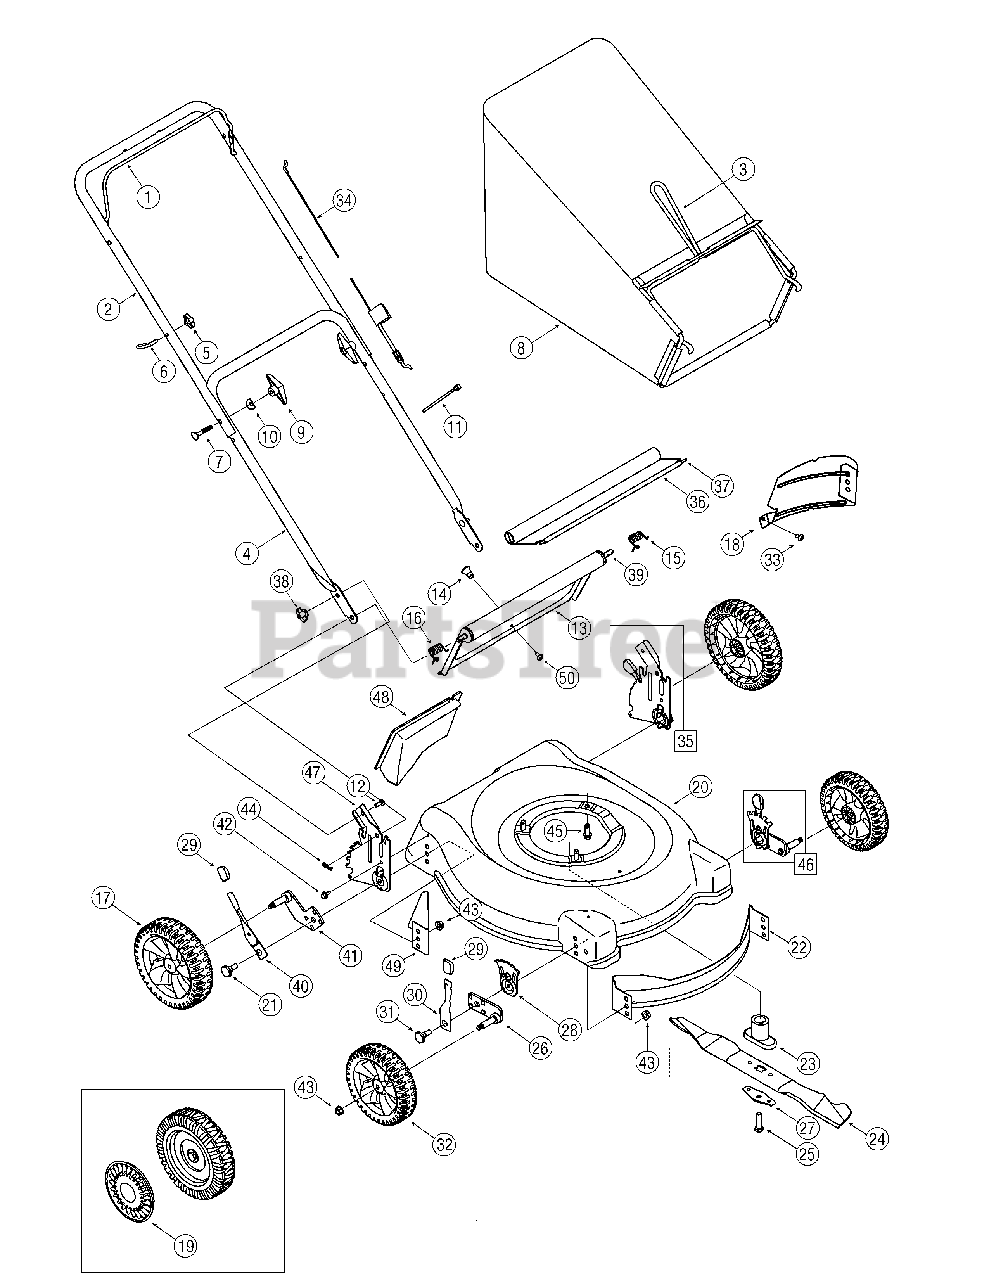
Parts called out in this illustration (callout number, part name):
1	Blade Control Handle
3	Grass Catcher Frame
4	Lower Handle
5	Wing Nut
6	Rope Guide
7	Carriage Bolt ,5/16-18 x 2
8	Grass Bag Assembly
9	Hand Knob
10	Saddle Washer
11	Cable Tie
12	Carriage Bolt ,1/4-20
13	Rear Discharge Door
15	Torsion Spring - LH
16	Torsion Spring - RH
17	Rear Wheel
18	Rear Baffle
19	Hubcap
20	Deck - 21"
21	Shoulder Screw
22	Front Baffle
23	Blade Adapter
24	Mulching Blade
25	Hex Bolt , 3/8-24 x 2.5
26	Pivot Arm Assembly -RH
26	Pivot Arm Assembly - LH
27	Blade Bell Support
28	Front Adjustment Plate
29	Adjustment Lever Knob
30	Spring Lever Assembly
31	Shoulder Screw
32	Front Wheel
33	Screw, 1/4-14 x .625
34	Control Cable - 37.25"
34	Control Cable - 40"
35	Rear Handle Bracket Assy. - LH
35	Rear Handle Bracket Assy. - RH
36	Trailshield
37	Trailshield Wire
38	Wing Nut, 1/4-20
39	Rear Door Pivot Rod
40	Spring Lever
41	Pivot Arm Assembly - RH
41	Pivot Arm Assembly - LH
42	AB Screw
43	Flange Lock Nut, 3/8-16
44	Hairpin Clip
45	TT Sems Screw, 3/8-16 x 1.0
46	Ht. Adj. Assy. Front - RH (7" Wheel)
46	Ht. Adj. Assy. Front - LH (7" Wheel)
47	Handle Bracket RH
48	Mulch Plug
49	Rear RH Baffle
50	Screw #10-24 x .375
